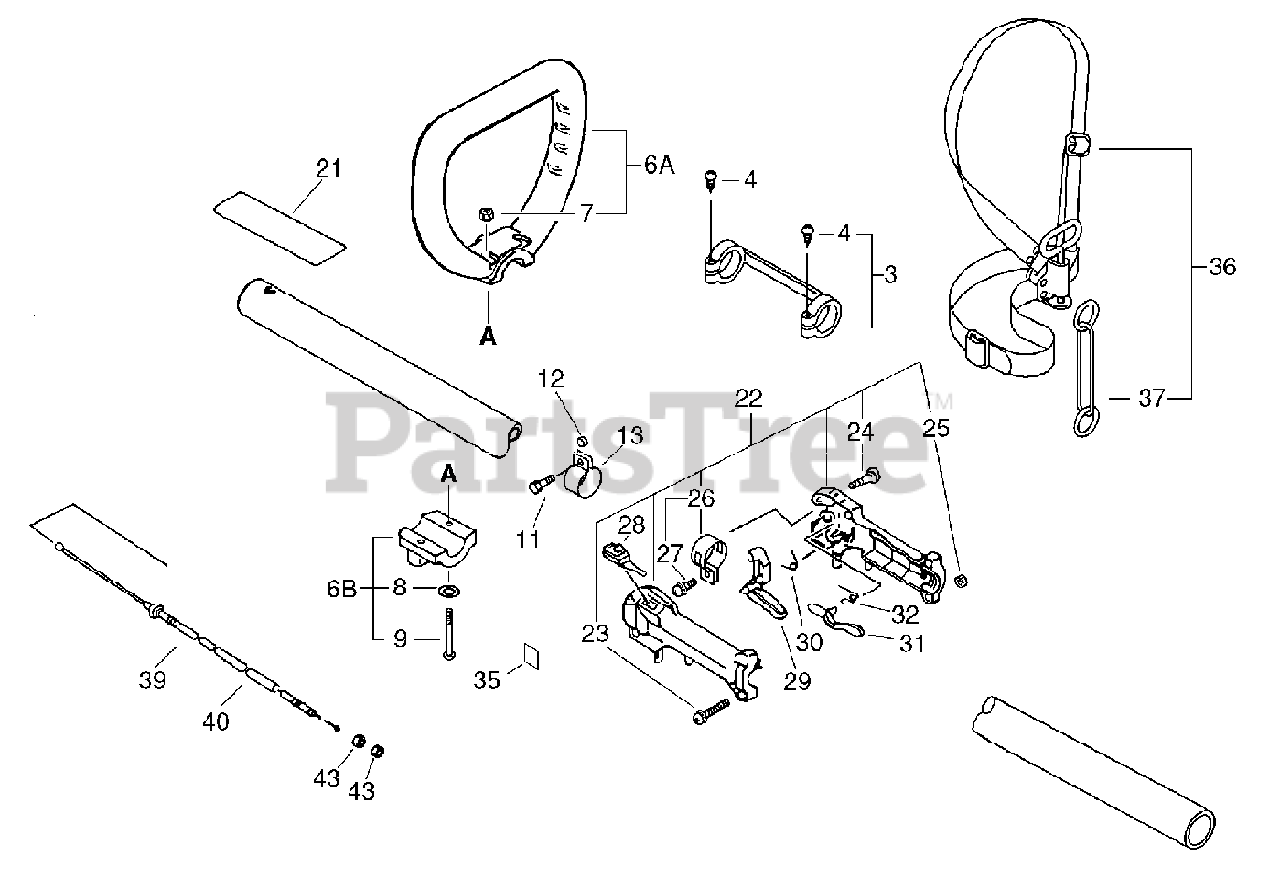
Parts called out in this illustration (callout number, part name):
4	Screw 4*25
6	Handle Assy, Loop
7	Nut 5
9	Screw 5*40
11	Bolt 5*18
21	Label,Caution
22	Grip Assy, F-Handle
23	Screw 5*25
24	Screw Tapping 4*18
25	Nut 5
26	Band Assy
27	Screw 5*12
28	Switch, Ignition
29	Control, Throttle
30	Spring, Thr. Return
31	Lockout, Throttle
32	Spring, Thr. Lockout
35	Label, Switch
36	Harness Asy,Shoulder
37	Link
39	Wire, Throttle
43	Nut 6 (3N)
